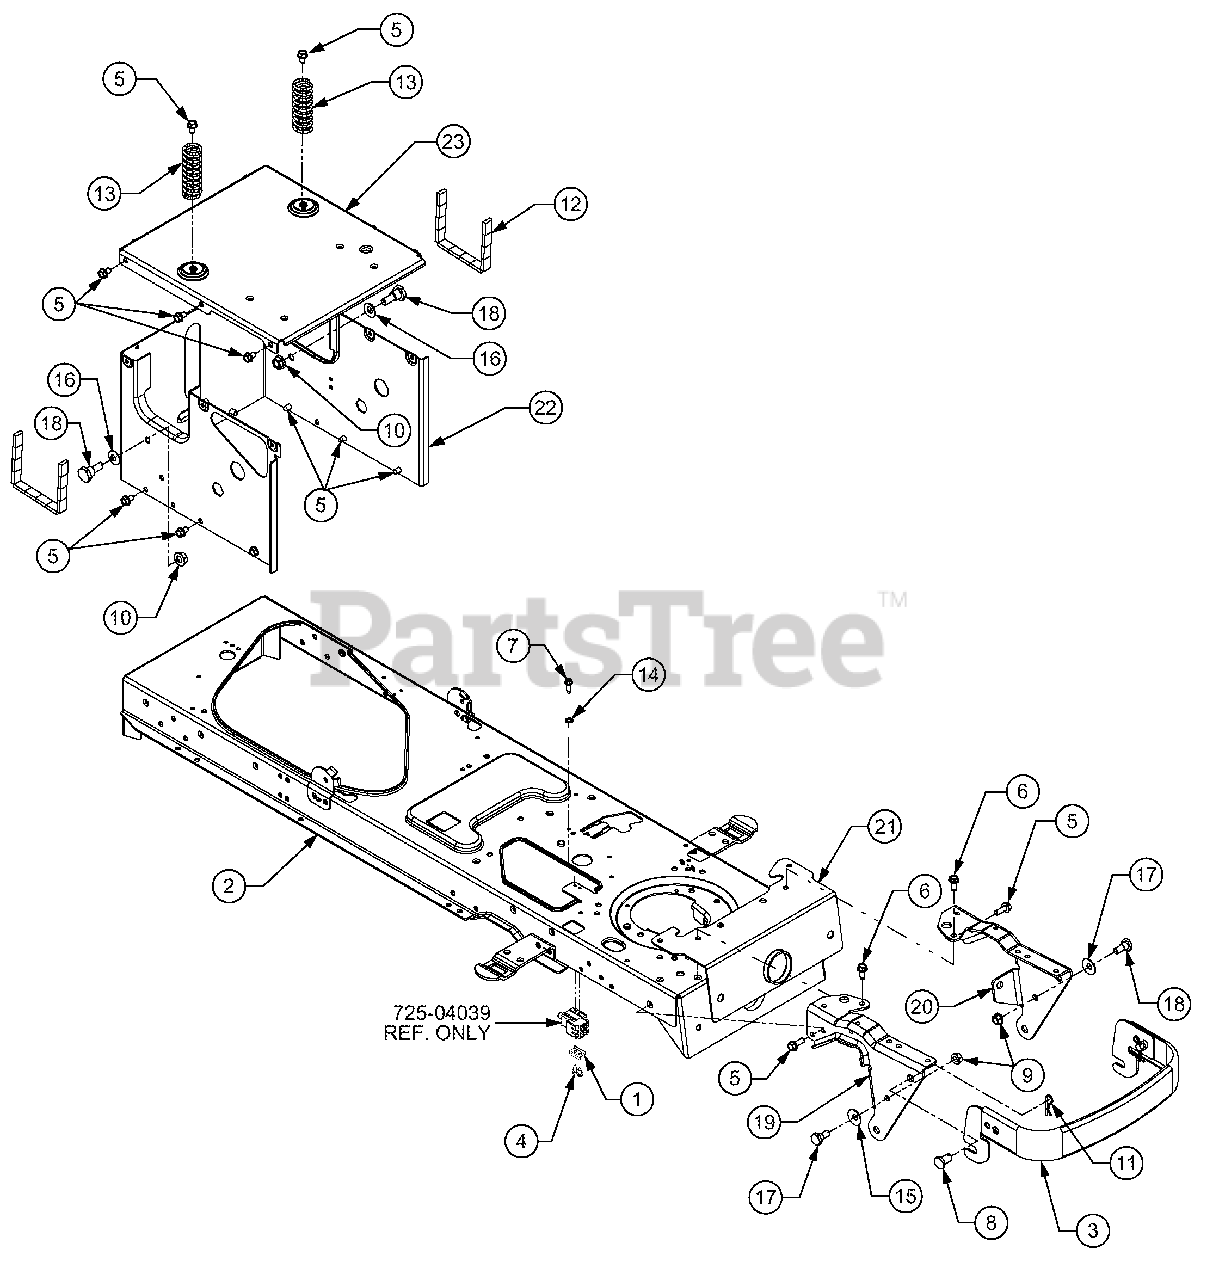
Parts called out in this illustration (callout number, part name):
1	Plate, Switch
5	Screw, Self-tapping, 5/16-18, 0.625
6	Screw, 5/16-18, 0.750
7	Screw, Hex Wash. Hd. Tapp, 1/4-20 x 0.625
8	Pin, Clevis, .50 Dia x .78 Lg
9	Nut, Flange Lock, 3/8-16
10	Nut, Flange Lock, 7/16-20
11	Pin, Click, .092 x 1.64 Lg
12	Foam Tape, .625 x .25
13	Spring, Compression, 1.28 OD x 3.125 Lg
14	Washer, Lock, Ext 1/4
15	Washer, Bell, .390 x 1.13 x .062
16	Washer, Bell .45 x 1.00 x .062
17	Shoulder Screw, 3/8-16
18	Shoulder Screw .625 x .500, 7/16-20
